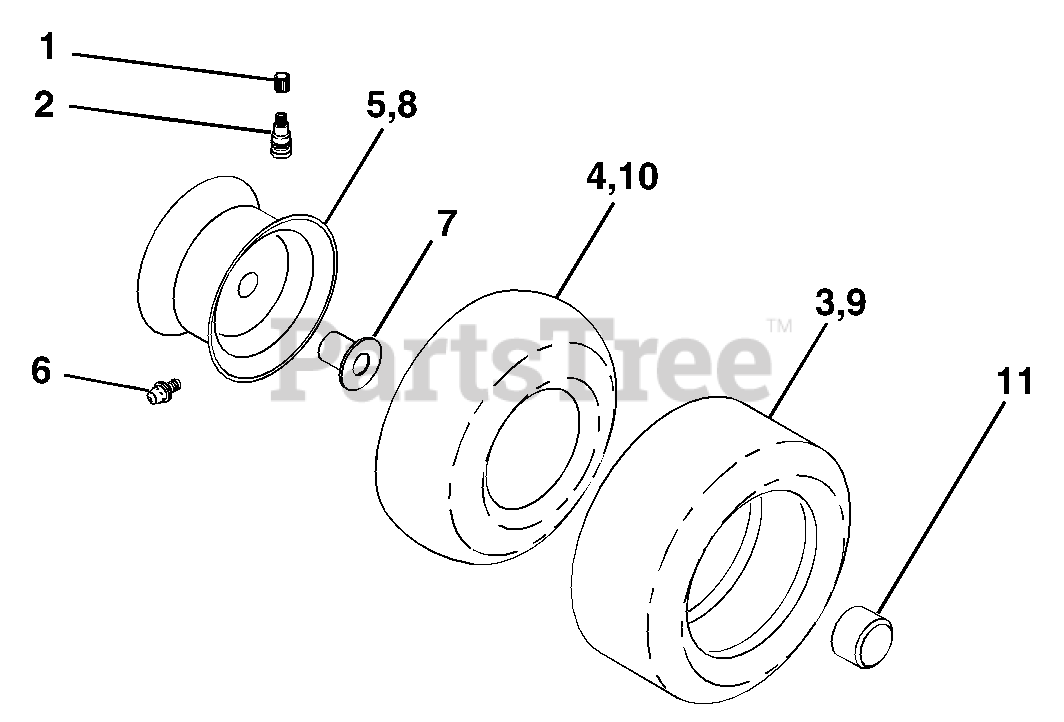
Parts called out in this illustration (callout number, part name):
1	Cap Valve Tire
2	Stem Valve
3	Tire FT 15 x 60 - 6 Service
4	Tube Front
5	Rim Asm 6" front Service
6	Fitting Grease
7	Bearing Flange
8	Rim Asm 8" rear Service
9	Tire RT 18 x 9.5-8 Service
10	Tube Rear
11	Cap Axle Blk 150 x 100
